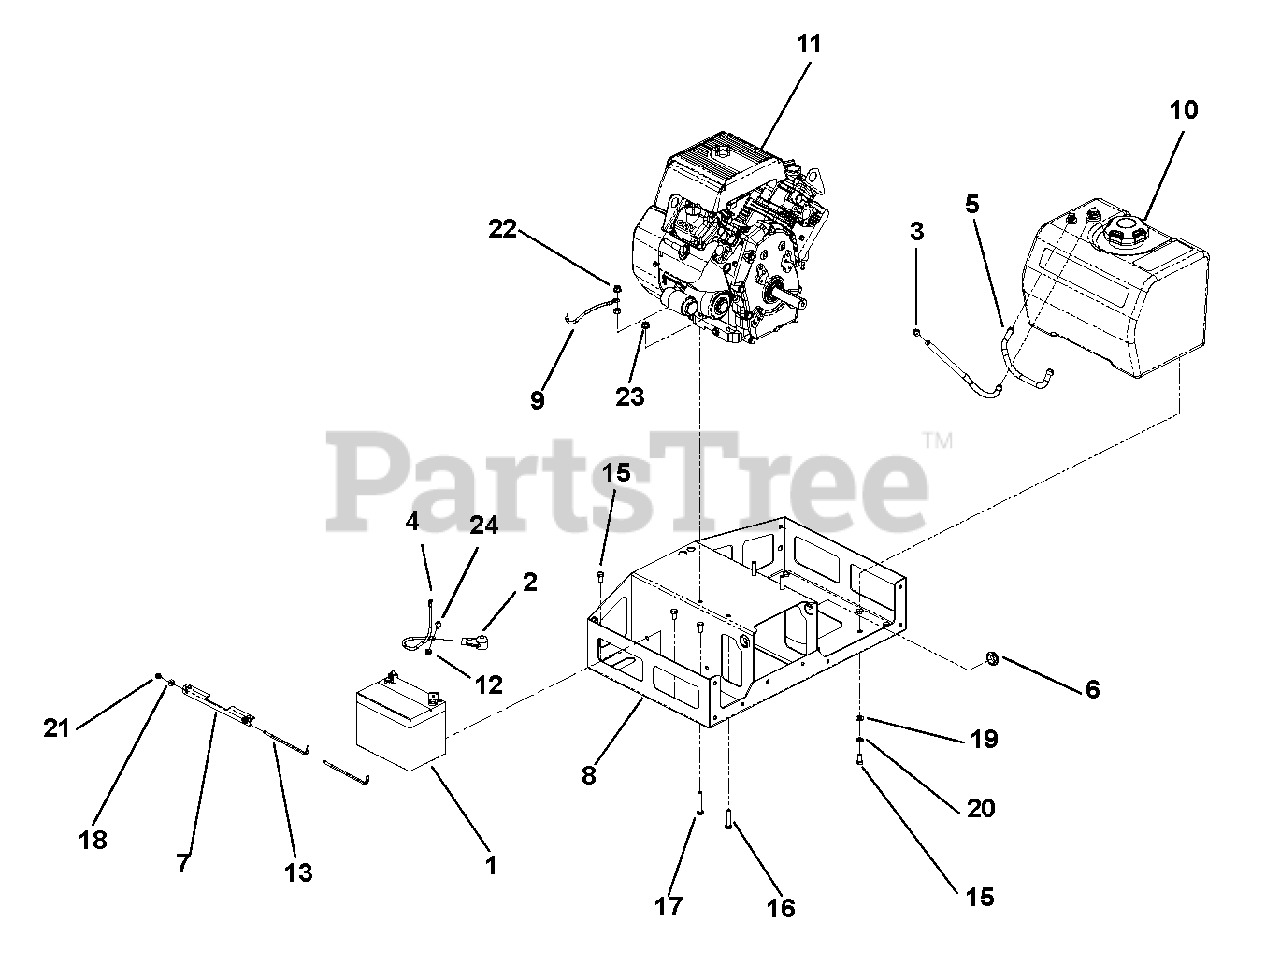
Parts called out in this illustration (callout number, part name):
1	Battery, 12V-U1-CCA270MIN
2	Battery Terminal Boot, Red
3	Clamp, Fuel Line
4	Cable, Positive Battery 9.00" REVA2
5	Gas Hose, Low Perm .25 x 18"
6	Grommet, Rubber .88 ID x 1.38 OD x .14 GR
7	Strap, Battery Hold Down
8	Weldment, Frame Base
9	Cable, Battery Negative 10" .25 x .37
10	Fuel Tank Assembly-Low Perm
11	Engine, Subaru 22 HP (995042)
12	Nut, Lock Flange .25-20 YWZC
13	J-Bolt, 1/4-20
14	Ring, Rubber Foot
15	Bolt, Hex .38-16 x .75 Grade 5 YWZC
16	Bolt, Hex .38-16 x 1.75 Grade 5 YWZC
17	Bolt, Hex .38-16 x 2.25 Grade 5 YWZC
18	Washer, Flat .281 x .62 x .065 Stl YWZC
19	Washer, Flat 1.010 x 1.505 x .062 Stl YWZC
20	Washer, Lock .38 x .094 Reg YWZC
21	Nut, Nyloc .25-20 YWZC
22	Nut, Nyloc Flange .38-16 YWZC
23	Nut, Hex .38-16 YWZC
24	Screw, Flange Head 1/4-20 x 5/8
